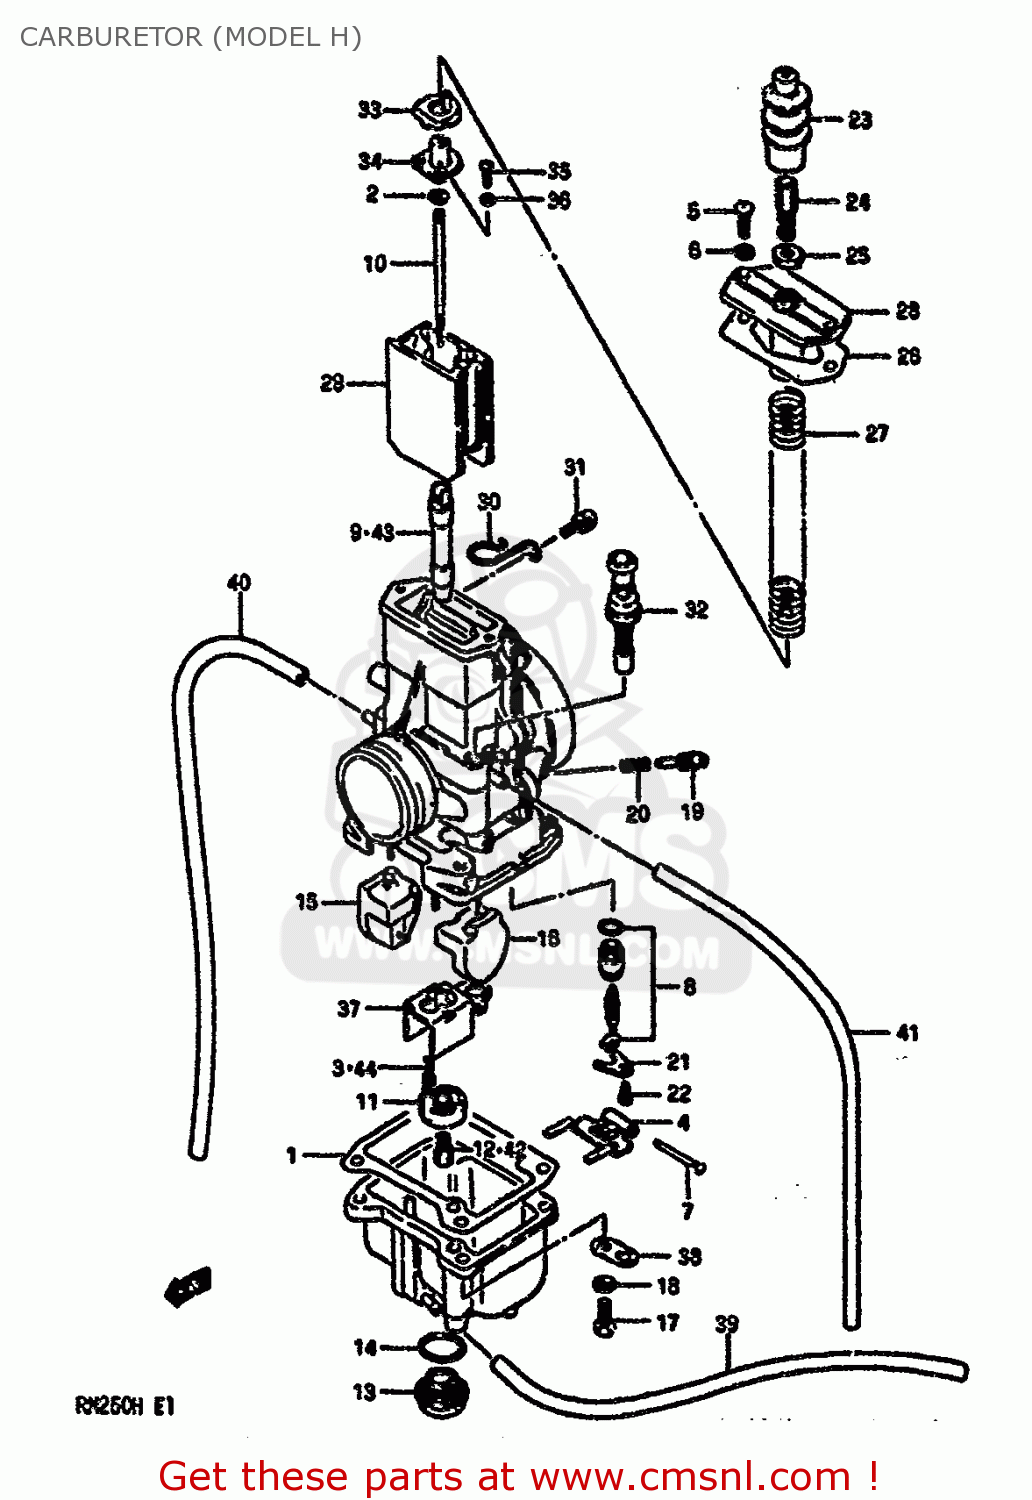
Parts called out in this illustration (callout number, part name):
1	GASKET,FLOAT CAHMBER (NAS)
2	CLIP,NEEDLE
3	JET,PILOT(35)
4	ARM,FLOAT
5	SCREW
6	LOCK WASHER
7	PIN,FLOAT
8	VALVE ASSY,NEEDLE
9	JET,NEEDLE
10	NEEDLE JET
11	RING
12	JET,MAIN(350)
13	SCREW,GUIDE
14	O RING,DRAIN PLUG
15	FLOAT,R
16	FLOAT,L
17	SCREW
18	LOCK WASHER
19	SCREW,PILOT AIR
20	SPRING
21	PLATE
22	SCREW
23	CAP,CABLE ADJUSTER
24	ADJUSTER,CABLE
25	NUT
26	GASKET,MIXING CHAMBER (NAS)
27	SPRING
28	CAP,CARBURETOR,TOP
29	VALVE
30	CLIP
31	SCREW
32	PLUNGER ASSEMBLY
33	SEAT,RETURN SPRING
34	PLATE,NEEDLE JET
35	SCREW
36	LOCK WASHER
37	PLATE
38	PLATE
39	HOSE
40	HOSE
41	HOSE
42	JET,MAIN(310)
43	JET,NEEDLE
44	JET
